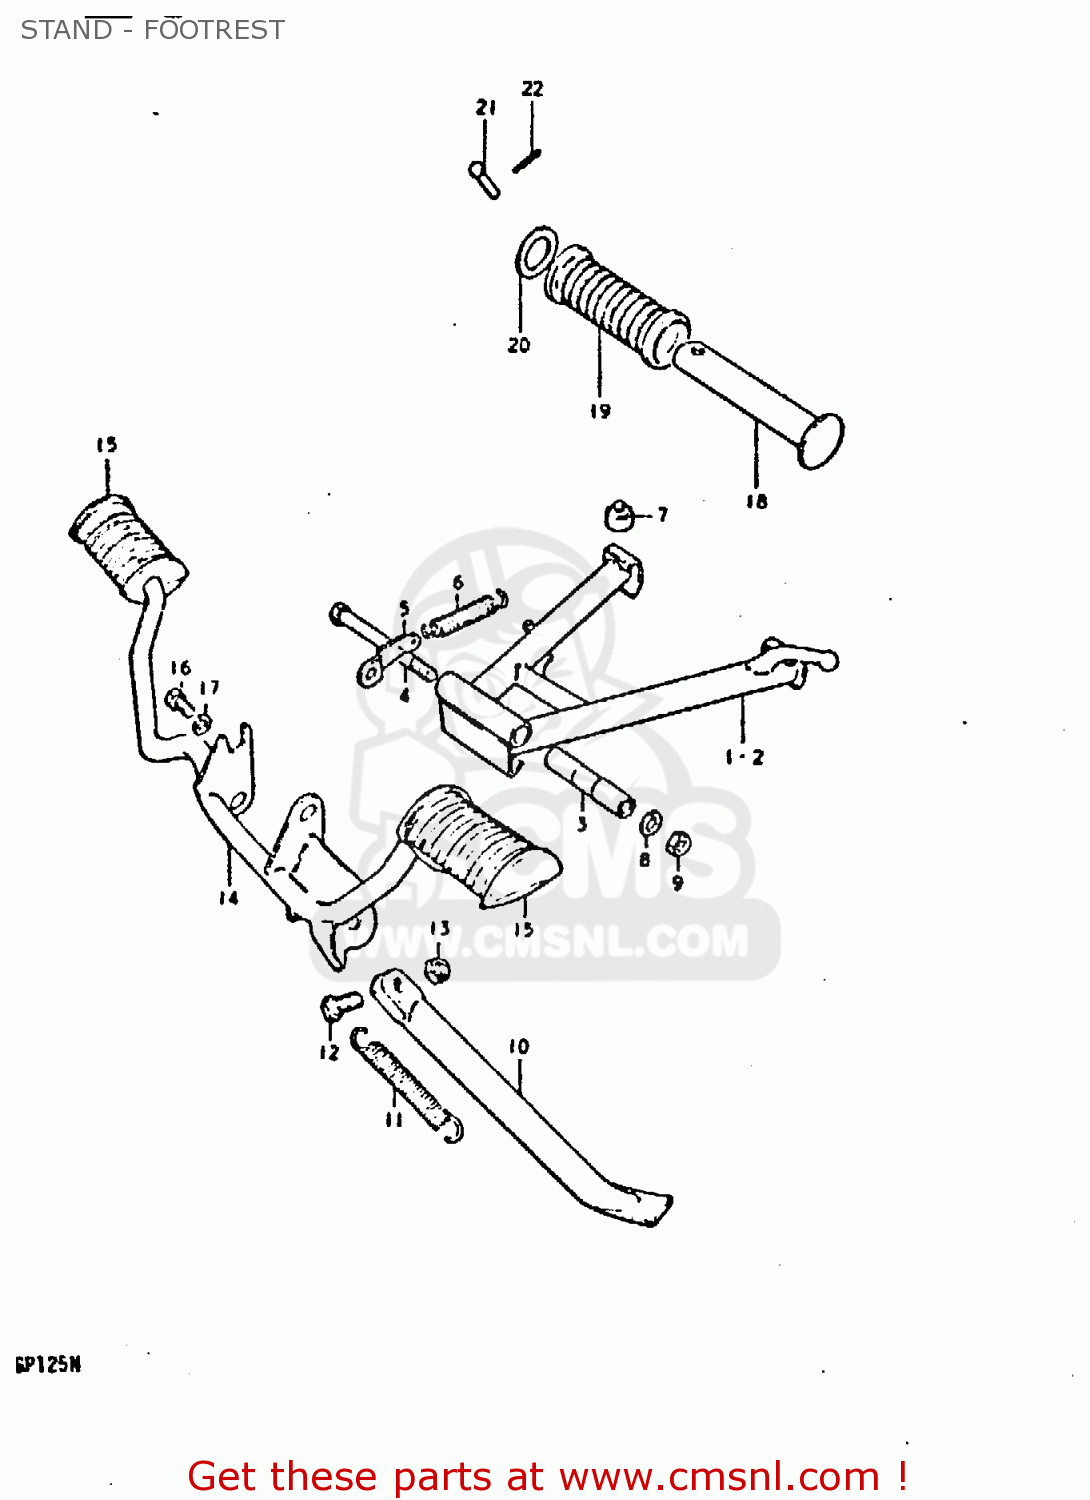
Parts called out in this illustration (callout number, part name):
1	STAND,CENTER
3	SPACER
4	BOLT(10X110)
5	HOOK,CTR STAND SPRING
6	SPRING
7	CUSHION
8	LOCK WASHER
9	NUT
10	STAND,PROP
11	SPRING
12	BOLT
13	NUT
14	BAR, FRONT FOOTREST
15	RUBBER,FR FOOTREST
16	BOLT
17	LOCK WASHER
18	BAR,FOOTREST RUBBER
19	RUBBER,PILLION FOOTREST
20	WASHER (19.5X32X2)
21	PIN
22	PIN 20X20
